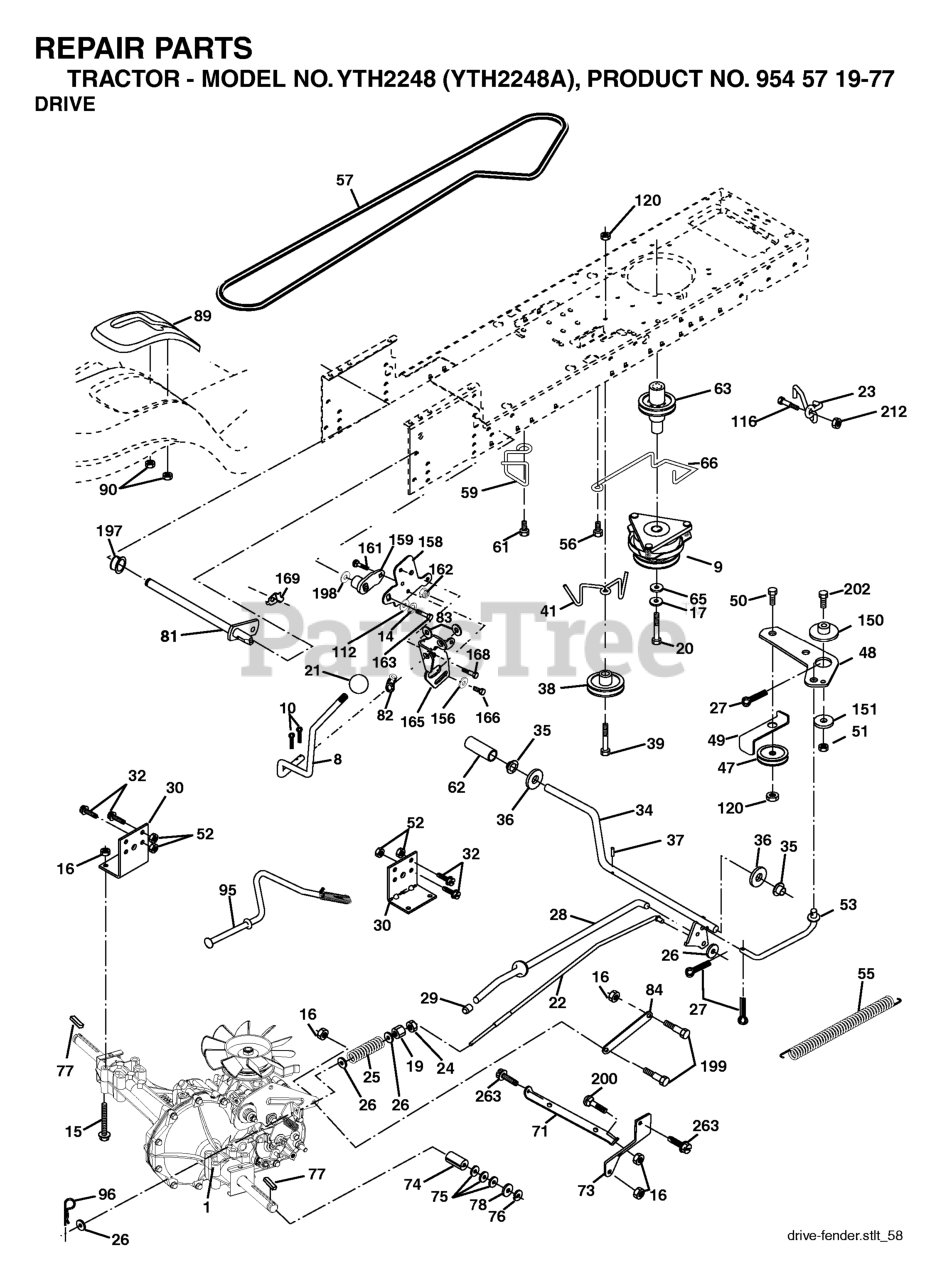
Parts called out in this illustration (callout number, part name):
8	ROD SHIFT FENDER ADJUST STLT
9	CLUTCH ELECTRIC
10	PIN COTTER
14	LOCKWASHER
15	BOLT HEX 5/16-18 GR 5
16	NUT.71038.31-18.HEX.NYLOCK
19	NUT
20	BOLT HEX 7/16-20X4-1/4"
21	KNOB.DELUXE.(PISTOL.GRIP).BLAC
22	ROD BRAKE HYDRO
23	BRKT ASM MTNG
24	NUT
25	SPRING ROD LT
26	WASHER
27	COTTER PIN
28	ROD, PARKING BRAKE
29	PLUNGER CAP
30	BRKT, TRNSXLE MNT 20"
32	BOLT
34	SHAFT, FOOT PEDAL
35	BEARING.NYLON
37	DRIVE PIN
38	PULLEY IDLER COMPOSITE
41	KEEPER, BELT IDLER
47	IDLER PULLEY
48	BELLCRANK, CLUTCH
49	RETAIN BELT
50	BOLT.3/8-16X1.50
52	LOCKNUT
53	LINK, CLUTCH LT
55	SPRING, RETURN LT
56	SCREW.3/8-16
57	DRIVE BELT, LTH & YTH TRACTORS
59	KEEPER, BELT CENTER
61	SCREW 3/8-16X.875
62	PEDAL COVER T
63	PULLEY- ENGINE
65	LOCKWASHER
66	KEEPER BELT ENGINE
71	STRAP TORQUE LH HYDRO
73	STRAP TORQUE RH HYDRO
74	SPACER AXLE
77	SQUARE KEY
81	SHAFT ASM CROSS TAPERED
82	SHIFT SPRING
83	WASHER
84	LINK TRANSAXLE
89	SHIFT CONSOLE
90	NUT.PUSH.3/16
95	CONTROL ASM. BYPASS HYDRO
96	RETAINER M
116	BOLT D
120	NUT LOCK FLG 3/8-16 UNC
150	SPACER, RETAINER
151	WASHER 12/32X2X10GA
156	WASHER.SRRTD.5/16
158	BRACKET
159	RB HUB.SHIFT
161	BOLT
162	NUT.CROWNLOCK.1/4
165	RP BRACKET
166	CAPSCREW.HXHD.FLG.5/16-18X.625
168	BOLT.SHOULDER.5/16-18X
169	PLATE.FASTENING.CROSS.SHAFT
197	NYLINER SNAP 5/8" ID
198	WASHER.NYL.7/8IDX.105"HYD CR
199	BOLT SHOULDER 5/16-18 UNC
212	NUT
263	SCREW, 3/8-16X3/4
